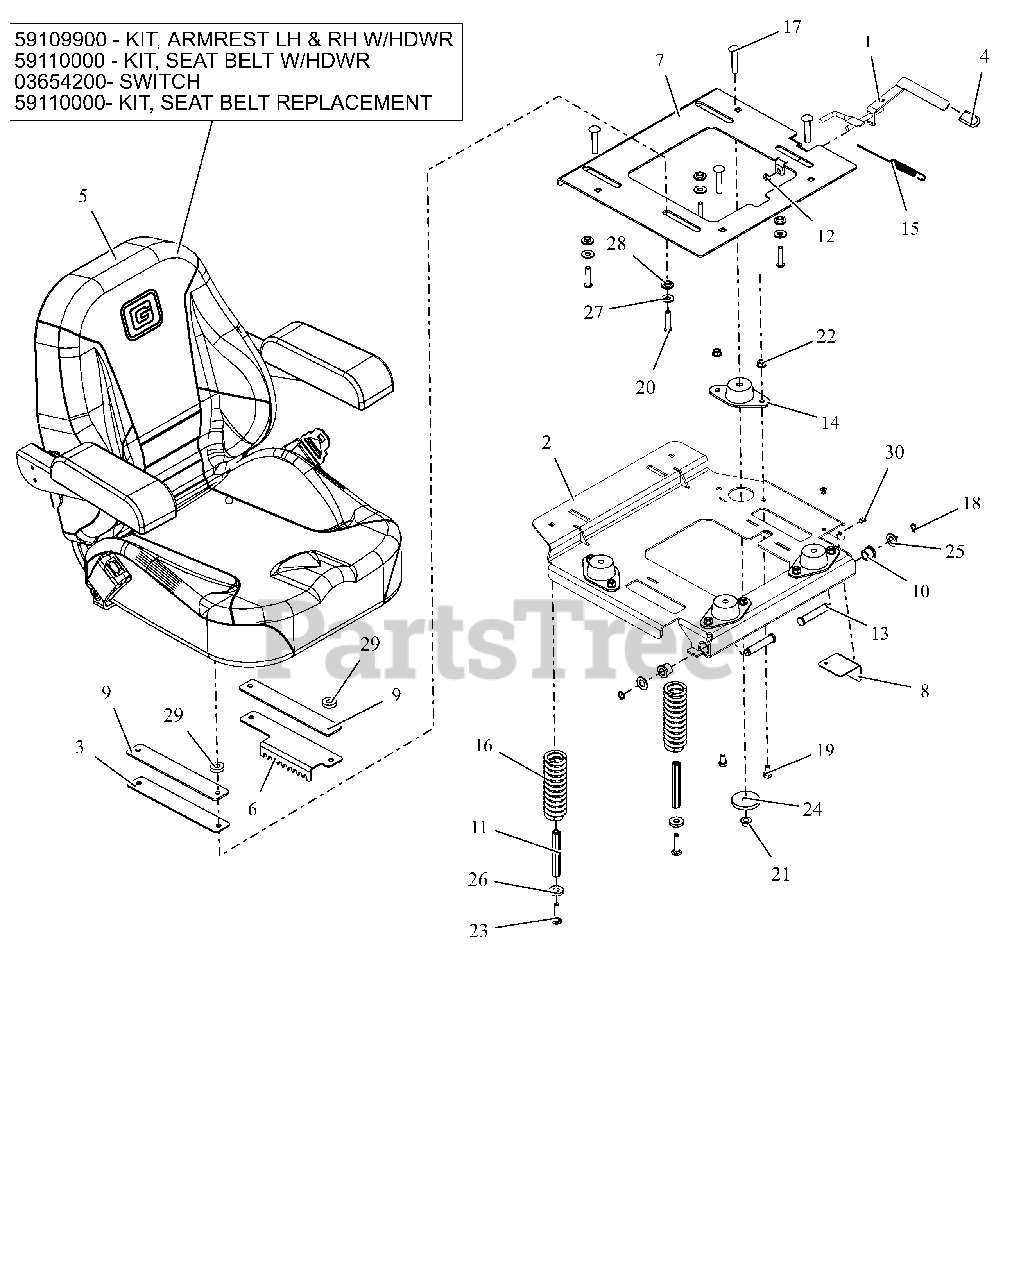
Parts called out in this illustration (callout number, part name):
1	WLDMT, SEAT SLIDE LEVER
2	WLDMT, ISO MTG PLATE (BLACK)
3	PLATE, ADJUSTABLE SEAT SLIDE
4	GRIP, SEAT LEVER, GREY
5	KIT, LH&RH ARM REST-05007300
5	KIT-SEAT BELT REPLACE-05007300
5	SWITCH- SEAT
6	PLATE, HD SEAT ADJUSTMENT
7	PLATE, SEAT MOUNTING (ISO KIT) (RED)
8	GUARD, SEAT FAN (BLACK)
9	SPCR, SEAT
10	BSHG, FLG .516X.750X.625X.937
11	NUT, COUPLING 5/16X18 X 3.75
12	NUT-PUSH .312
13	PIN, SEAT PIVOT -.500X2.31
14	MOUNT, FAIL-SAFE COMPRESSION
15	SG-TENS .06X.482X5.35
16	SPRING, COMPRESSION SEAT 224LB
17	BLT-RDHDSQNK .38-16X2.00 SHTYW
18	RG-RTNG-EXT .500X.050 (SNAP)
19	BLT, HEX .31-18X.625 G5 ZCC
20	SCR,BTNHD .31-18X1.50 ZCC
21	NUT-LK-CTR-FLG .375-16 GF ZCC
22	NUT,LK-CTR-FLG .31-18 GF ZCC
23	BLT,RHSN .31-18X1.50 G5 ZCC
24	WSHR, FLT .469X2.00X.250 ZCC
25	WSHR, FLT .531X1.00X.063 ZCC
26	WSHR, FLT .406X1.00X.188 ZCC
27	WSHR,FLT .375X.875X.083 ZCC
28	BSHG-FLG .325X.499X.3X.875
29	WSHR-FL-STL,.390X1.00X.25 YWZC
30	RIVET, .1875 AL/AL .126-.250
